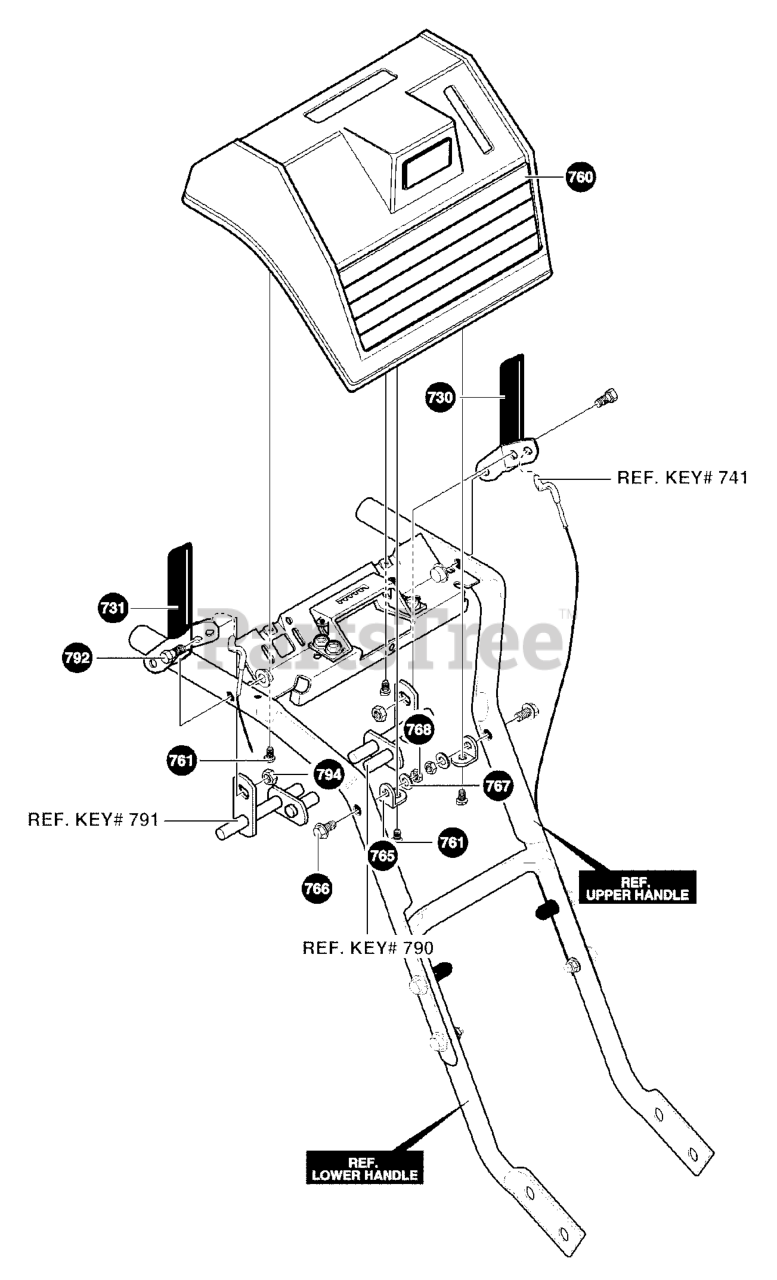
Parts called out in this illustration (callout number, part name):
730	CLUTCH HANDLE LH
731	CLUTCH HANDLE RH
761	SCREW, 10 X .62
765	BRACKET, PANEL
766	SCREW, 5/16-18 x 1.75
767	WASHER, HVSPTLK
768	NUT, 5/16-18
792	BOLT, 1/4-20 X .50
794	NUT, 1/4-20
